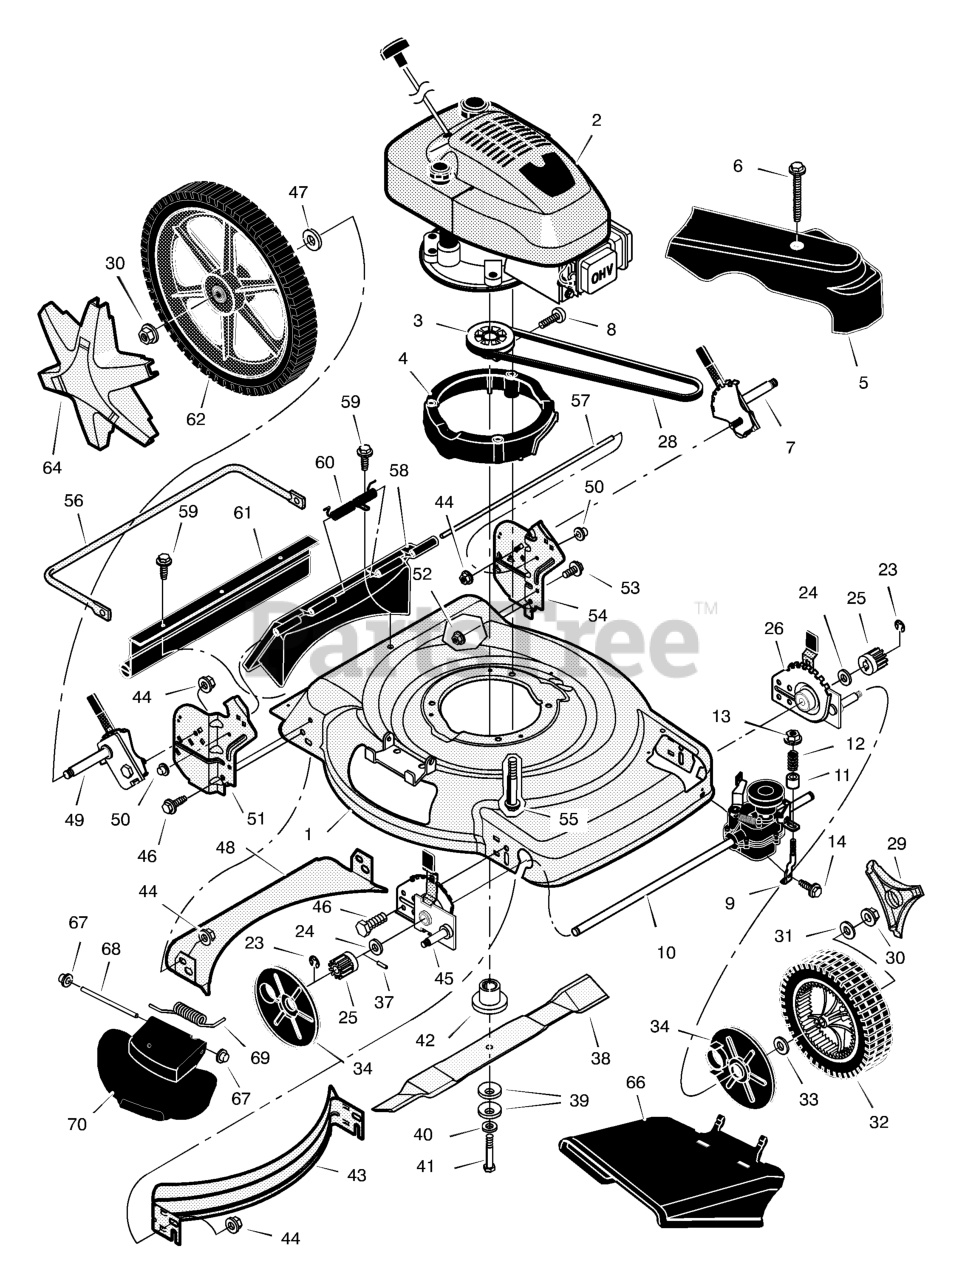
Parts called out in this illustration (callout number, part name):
1	Housing
2	Engine *
3	Pulley, Drive
4	Spacer, Engine
5	Cover, Belt (Gray)
7	Adjuster, Left Rear Height
9	Support, Spring
10	Transmission *
12	Spring, Compression
13	Nut
25	Gear, Pinion
26	Adjuster, Left Front Height
29	Cap, Hub
30	Nut, Flange
31	Washer
32	Wheel & Tire, Front
34	Cover, Dust
37	Pin, Drive
39	Washer, Belleville
42	Adapter, Blade
43	Baffle, Front
44	Nut, Flange
45	Adjuster, Right Front Height
46	Bolt
48	Baffle, Rear
49	Adjuster, Right Rear Height
50	Push On Cap
51	Bracket, Right Handle
52	Nut, Flange
53	Bolt
54	Bracket, Left Handle
55	Bolt, Engine
57	Rod, Pivot
58	Door, Rear (Gray)
60	Spring
61	Guard, Rear
62	Wheel & Tire, Rear
64	Cap, Hub
66	Deflector, Chute (Gray)
67	Push On Cap
68	Rod, Pivot
69	Spring, Torsion
70	Cover, Mulch (Gray)
